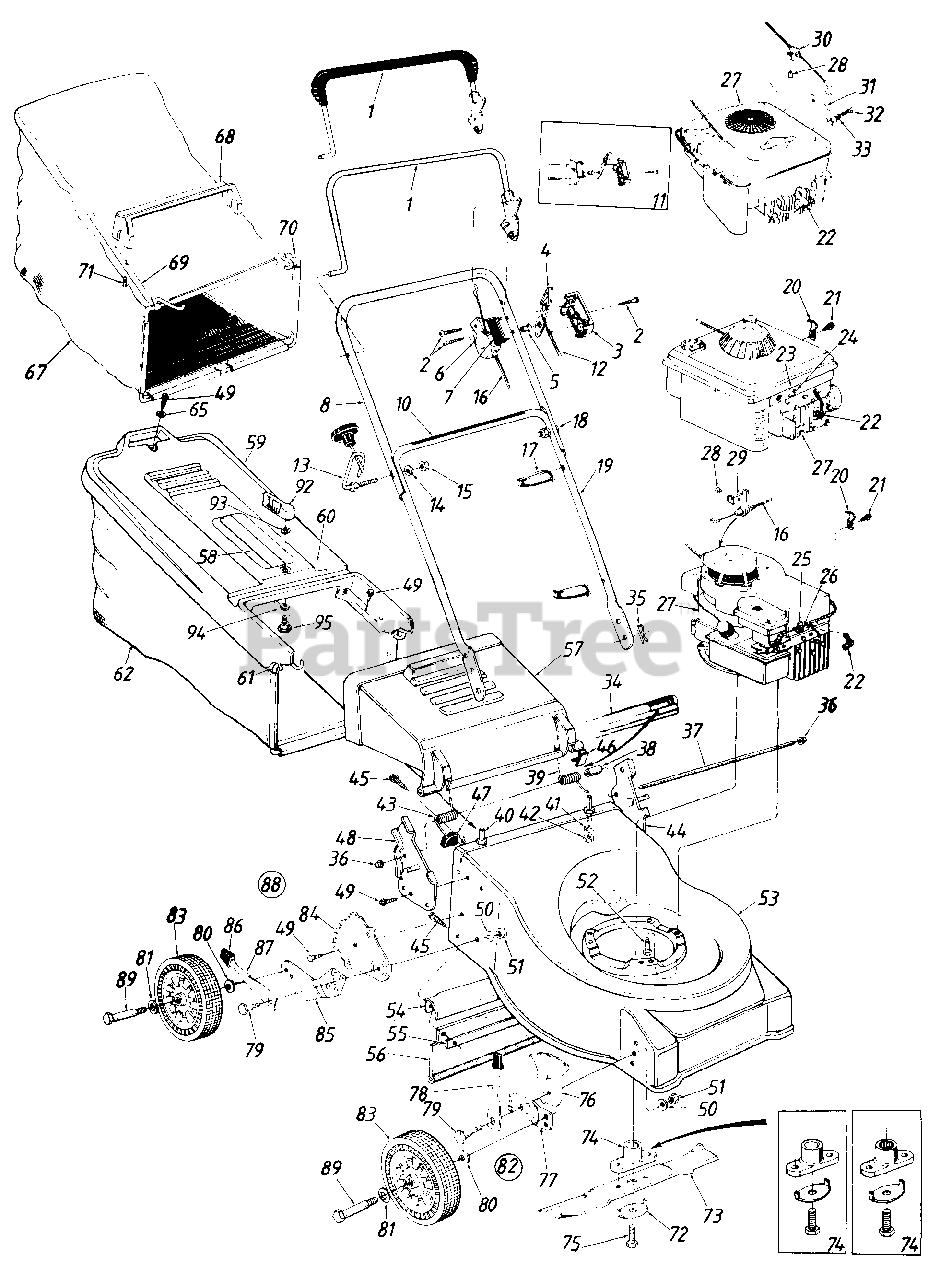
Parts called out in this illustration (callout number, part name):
1	Control Handle Ass'y.
2	Truss Mach. B-Tap Scr. #12 x 1.5" Lg.
3	Control Panel Half
4	Throttle Control Lever
5	Control Disc Pin
6	Clutch Panel Half
7	Control Label-Throttle
8	Upper Handle (Painted)
10	Instruction Label-Handle
11	Control Housing Comp.
12	Throttle Wire-58" Lg.
13	Rope Guide Bolt
14	L-Wash. 5/16" I.D.
15	Hex Nut 5/16-18 Thd.
16	Control Cable-43" Lg.
17	Cable Tie
18	Curved Carriage Bolt 5/16-18 x 1.38" Lg.
19	Lower Handle (Painted)
20	Cable Clamp
21	Hex B-Tap Scr. #10 x .38" Lg.
22	Spark Plug Boot
23	Cable Clamp
24	Hex B-Tap Scr. #10 x .62" Lg.
25	Cable Clamp
26	Hex AB-Tap Scr. #8 x .5" Lg.
27	Engine
28	Pop Rivet .156" Dia.
29	Cable Bracket
30	Cable Mtg. Brkt.
31	Mounting Brkt.
32	Truss Mach. Scr. #10 x .5" Lg.
33	L-Wash. #10 I.D.
34	Seal-Extrusion
35	Int. Cotter Pin 5/16" Dia.
36	Cap Speed Nut
37	Hinge Pin 17.75" Lg.
38	Spacer.255" I.D.
39	Torsion Spring-L.H.
40	Shld. Pin 3/8-24 x 1.43" Lg.
41	L-Wash. 3/8" I.D.
42	Hex Jam Nut 3/8-24 Thd.
43	Torsion Spring-R.H.
44	Handle Brkt. Ass'y.-L.H.
45	Torx Mach. AB-Tap Scr. 1/4 x .62" Lg.
46	Deflector Plug
47	Corner Plug
48	Handle Brkt. Ass'y.-R.H.
49	Hex L-Wash. AB-Tap Scr. 1/4 x.62" Lg.
50	Bell-Wash. .39" I.D. x 1.38" O.D.
51	Hex Nut 3/8-16 Thd.
52	Hex L-Wash. Hd. Scr. 3/8-16x 1" Lg.
57	Rear Chute Deflector
58	Hardtop Handle
59	Hardtop Bag Cover
60	Rear Catcher Frame
61	Front Catcher Frame
62	Grass Bag
65	Fl-Wash. .281" I.D.
67	Grass Bag
68	Bag Handle
69	Rear Catcher Frame
70	Front Catcher Frame
71	Hex AB-Tap Scr. #12 x 1.25" Lg.
72	Blade Bell-Wash. .44" I.D. x 2.38"
73	21" Blade
74	Blade Adapter Kit (Keyed)
75	Hex Bolt 3/8-24 x 1.5" Lg.
76	Height Adj. Plate
78	Spring Lever Ass'y. w/Knob
79	Shld. Bolt .50" Dia. x .357"
80	Bell-Wash. .38" I.D. x .88" O.D.
81	Fl-Wash. .531" I.D.
82	Height Adj. Ass'y. Comp.-R.H.
83	Wheel Ass'y. Comp.
84	Index Plate
85	Pivot Bar-R.H.
86	Spring Lever Knob
87	Spring Lever
88	Rear Height Adj. Ass'y. Comp.-R . H .
89	Axle Bolt
92	Grass Catcher Locking Knob
93	Internal L-Wash. 1/4" I.D.
94	Wave Washer 3/8" I.D.
95	Shld. Bolt .342" Dia. x .268"
